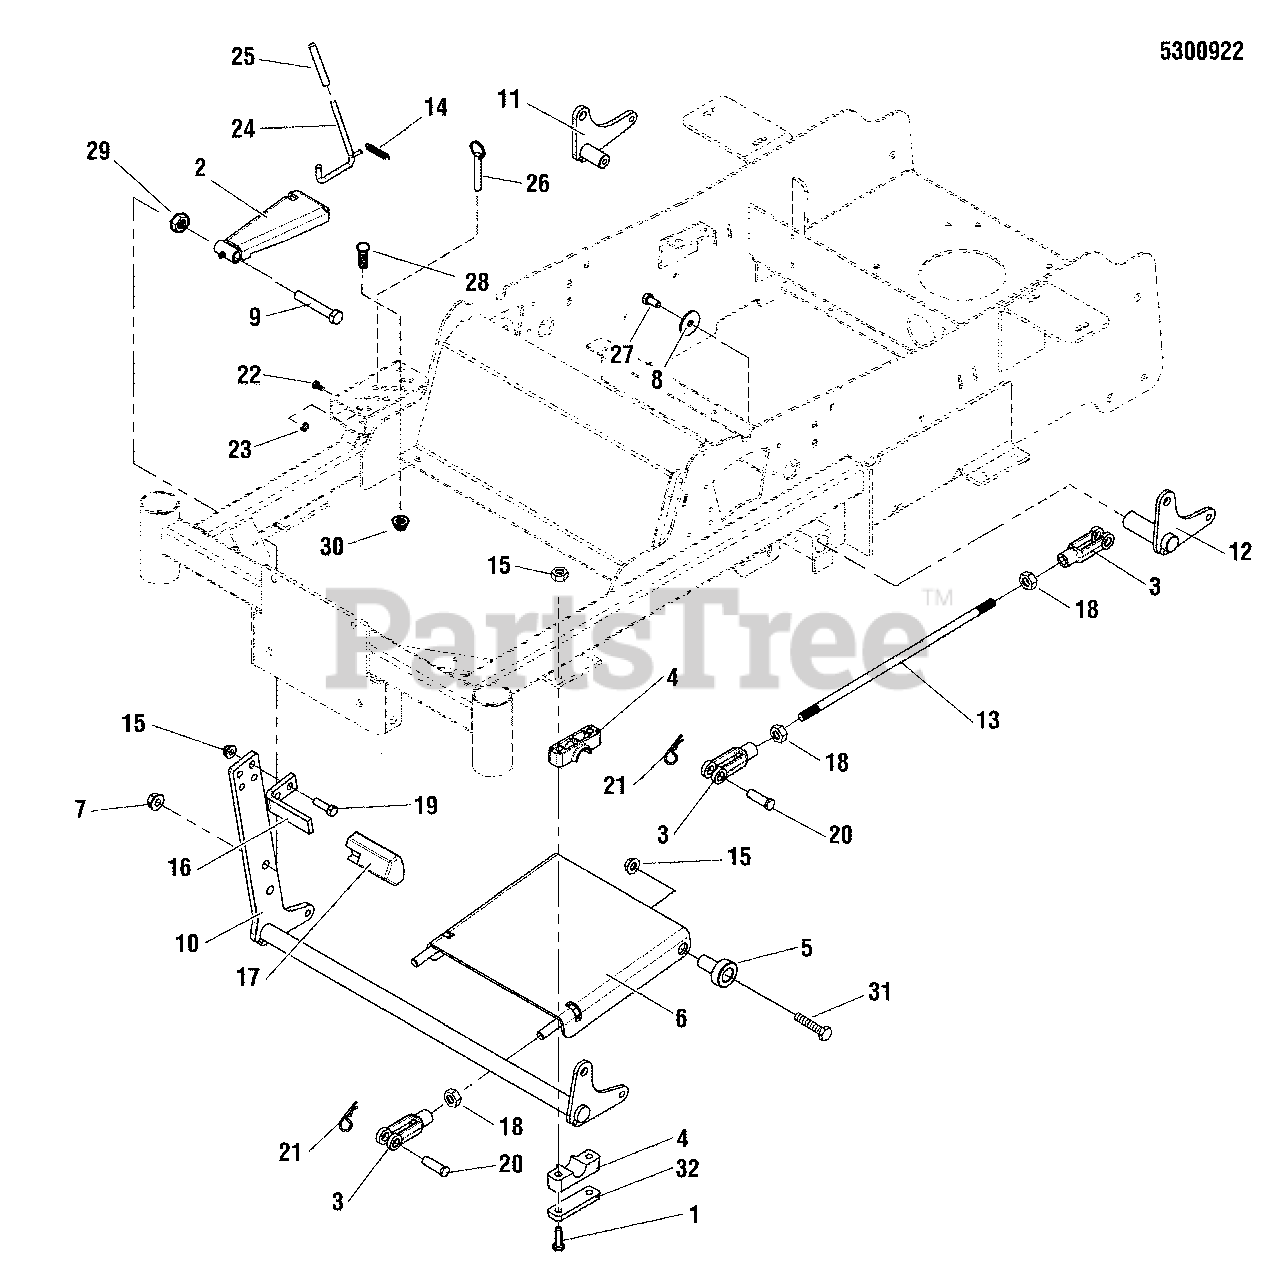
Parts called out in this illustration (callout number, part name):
1	BOLT, 3/8-16 X 1-1/2" GD5 CZ
2	WELD, DECK HEIGHT ADJUSTMENT - RED
3	CLEVIS, 1/2-20, STEEL
4	PIVOT BLOCK, PLASTIC
5	BUSHING, .38 X .88 X .73
6	WELD, PULLER BAR - RED
7	NUT, 1/2-13 HEX NYLOCK FLANGE
8	WASHER, .390 X 1.50 X .109, YZ
9	BOLT, 1/2-13 X 3" GD5 CZ
10	WELD, FRONT DECK PIVOT - RED
11	WELD, PIVOT DECK LIFT, RH - RED
12	WELD, PIVOT, DECK LIFT, LH - RED
13	ROD, DECK LIFT, SNAPPER PRO
14	SPRING, RETURN
15	NUT, 3/8-16 HEX NYLOCK FLANGE
16	PEDAL, FOOT - RED
17	RUBBER, FOOT PEDAL
18	NUT, 1/2-20 HEX JAM
19	BOLT, 3/8-16 X 1-1/4" GD5 CZ
20	PIN, CLEVIS, 1/2 X 1.36" SAE STANDARD
21	PIN, COTTER, 1/8 X 3/4
22	BOLT, 1/4-20 X 5/8", GD5 YZ
23	NUT, 1/4-20 HEX NYLOCK FLANGE
24	WELD, DECK TRANSPORT LEVER - RED
25	COVER, VINYL HANDLE
26	HITCH PIN, 3/8 X 2-1/2
27	BOLT, 3/8-16 X 3/4, GD5, YZ WITH PATCH
28	BOLT, 3/8-16 X 1-3/4", CARRIAGE
29	NUT, 5/16-18 HEX NYLOCK FLANGE
30	NUT, 1/2-13 HEX
31	BOLT, 3/8-16 X 1-1/2" GD5 CZ
32	PLATE, PIVOT BLOCK SUPPORT - RED
